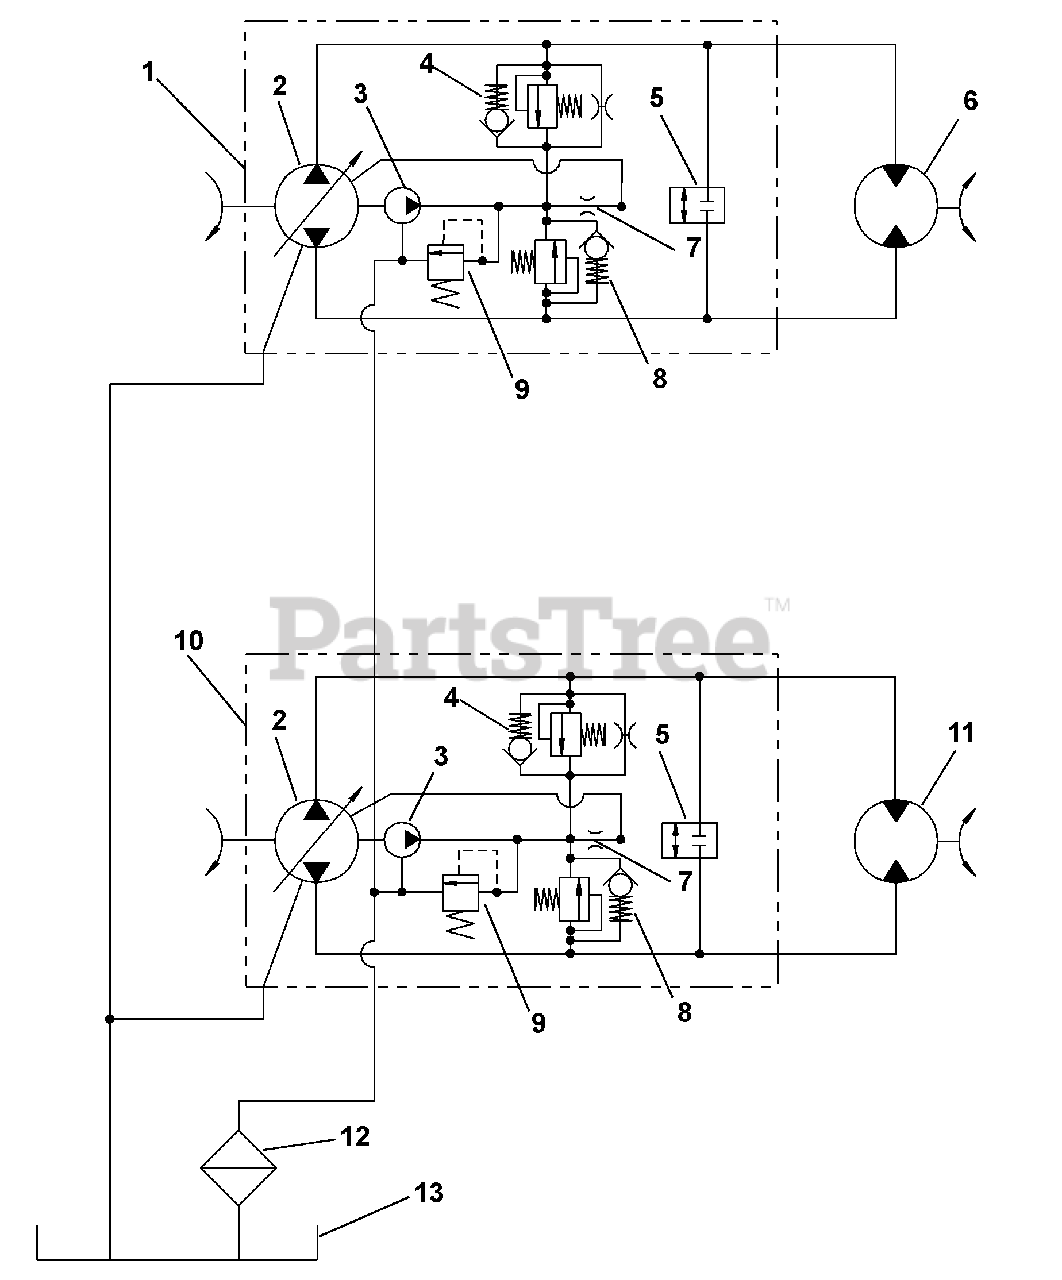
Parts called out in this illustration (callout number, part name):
1	Left Hydrostatic Pump Assembly
2	Pump Block
3	Charge Pump
4	System Change Check Shock Valve (Reverse)
5	Manual Bypass
6	Left Wheel Motor
7	Cooling Orifice
8	System Change Check Shock Valve (Forward)
9	Charge Relief Valve
10	Right Hydrostatic Pump Assembly
11	Right Wheel Motor
12	Inlet Filter
13	Hydraulic Reservoir
